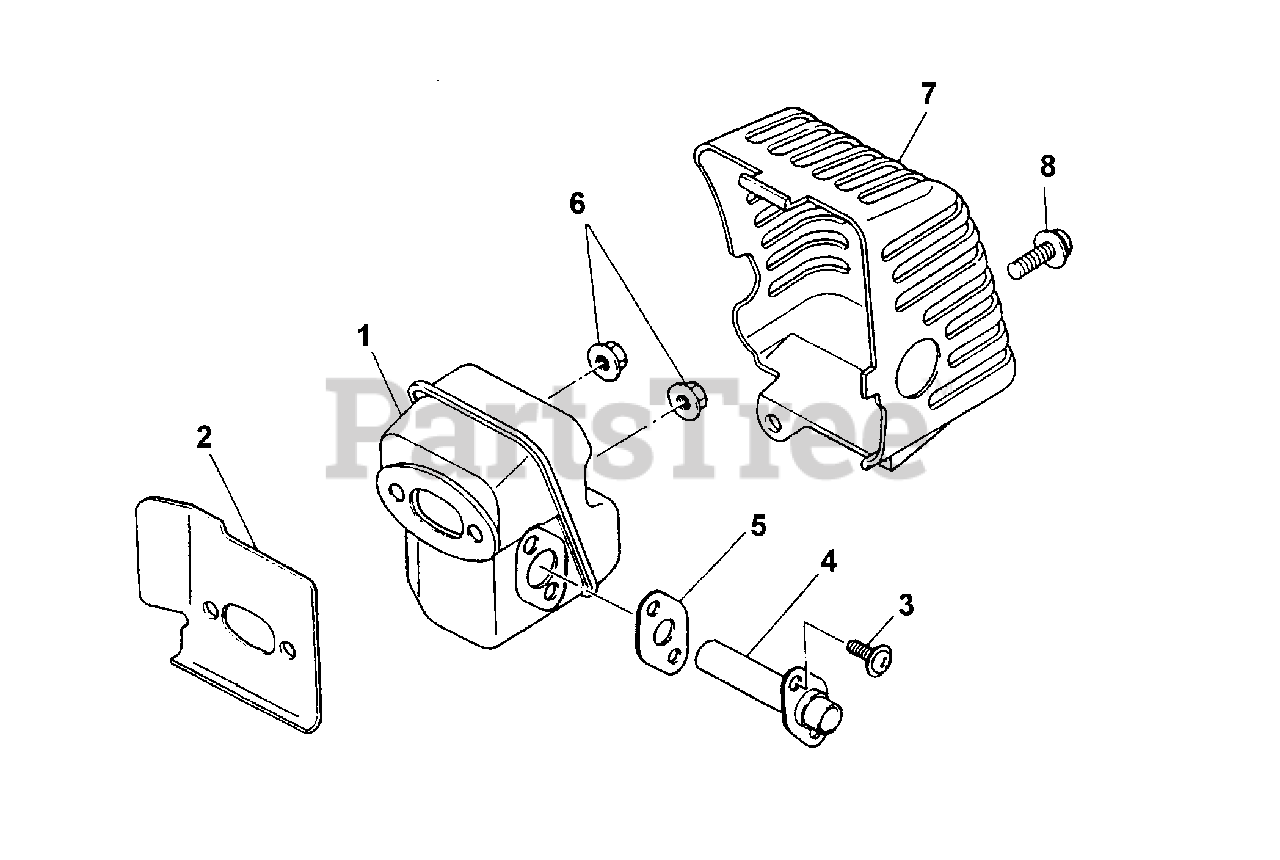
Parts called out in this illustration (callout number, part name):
1	MUFFLER ASSY.
2	GASKET, MUFFLER
3	SCREW & WASHER
4	TAIL PIPE
5	GASKET, TAIL PIPE
6	NUT, FLANGE
7	COVER, MUFFLER
8	SCREW & WASHER
